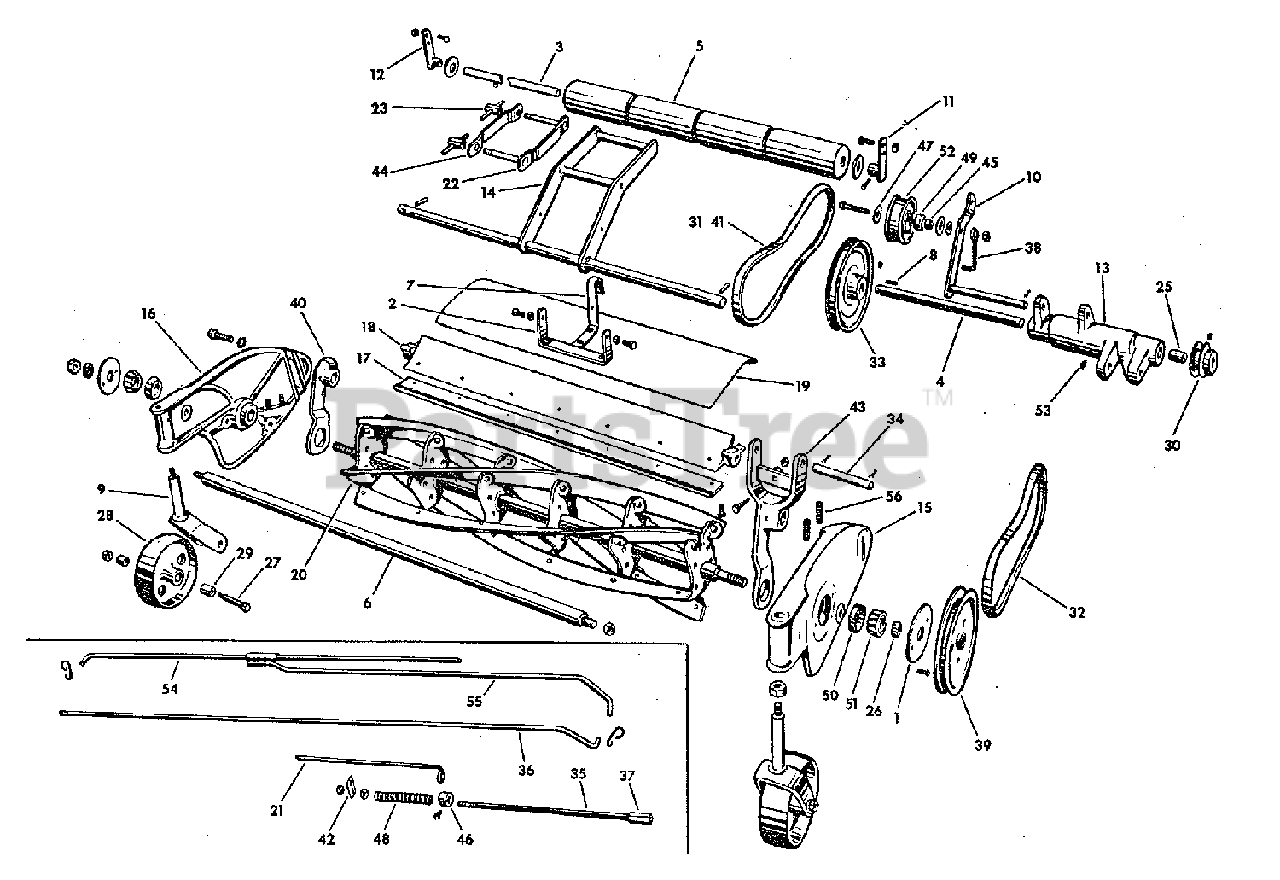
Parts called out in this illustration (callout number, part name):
1	CAP, Bearing
2	BRACKET, Grass Guard
3	SHAFT, Roller
4	SHAFT, Transmission
5	ROLLER, Hard Wood
6	ROD, Spacer
7	HANGER, Grass Guard
8	SHAFT KEY, Transmission
9	FORK ASSEMBLY, Roller
10	LEVER ASSEMBLY, Idler
11	ROLLER BRACKET, L.H.
12	ROLLER BRACKET, R.H.
13	BRACKET, Bearing
14	BAR ASSEMBLY, Draw
15	LAWN MOWER FRAME, L.H.
16	LAWN MOWER FRAME, R.H.
18	CASTING, Blade
19	GUARD, Grass
20	REEL ASSEMBLY
21	ROD, Clutch
22	SIDE PLATE, Hitch
23	NUT, Wing, Complete
24	CLIP, Spring
26	SPACER, Bearing
27	WHEEL SPINDLE, Caster
28	WHEEL, Caster
29	BUSHING, Caster Wheel
30	SHEAVE, Reel Driver
32	BELT, Reel Drive
33	SHEAVE, Counter Shaft
34	PIN, Hinge
35	IDLER ROD, Adjusting
36	IDLER ROD, Long
37	NUT, Coupling
38	HOLDER, Belt
39	SHEAVE, Reel
40	PUSH ARM, Right
41	BELT, Drive
42	ROD, Holder
43	PUSH ARM, Left
44	CLAMP, Hitch
45	INNER BEARING, Race
46	COLLAR, Set
47	WASHER, Thrust
48	SPRING, Idler Rod
49	BEARING, Idler Pulley
50	CUP, Bearing
51	CONE, Bearing
52	PULLEY, Idler
54	IDLER ROD, Lower
55	ROD ASSEMBLY, Upper
